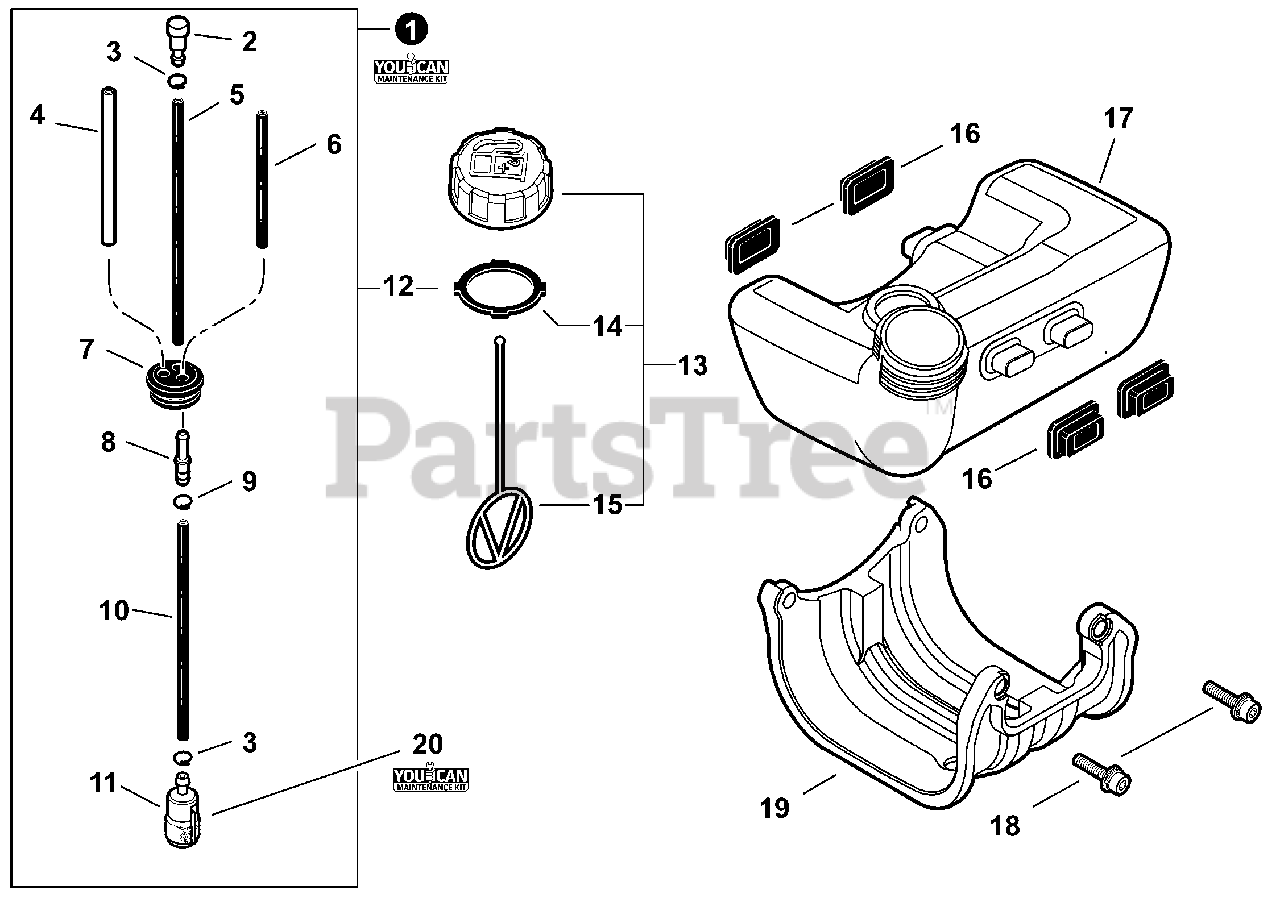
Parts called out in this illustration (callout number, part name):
1	FUEL SYSTEM KIT - YOUCANT
2	VENT ASSY
4	PIPE, FUEL 3x6x80 YELLOW
5	PIPE 3x6x90 MM
6	PIPE, FUEL - 3x5x67 - BLACK
7	GROMMET, FUEL
8	CONNECTOR, PIPE 5x3.5
9	CLIP 6.5 MM
10	PIPE, FUEL 3x6x120 BLACK
11	FILTER, FUEL
12	GASKET, FUEL CAP
13	CAP ASSY, FUEL
14	GASKET, FUEL CAP
15	CONNECTOR, CAP L= 123
16	CUSHION, FUEL TANK
17	TANK, FUEL
18	BOLT M5x20
19	GUARD, PLASTIC FUEL TANK
20	TUNE-UP KIT - YOUCANT
